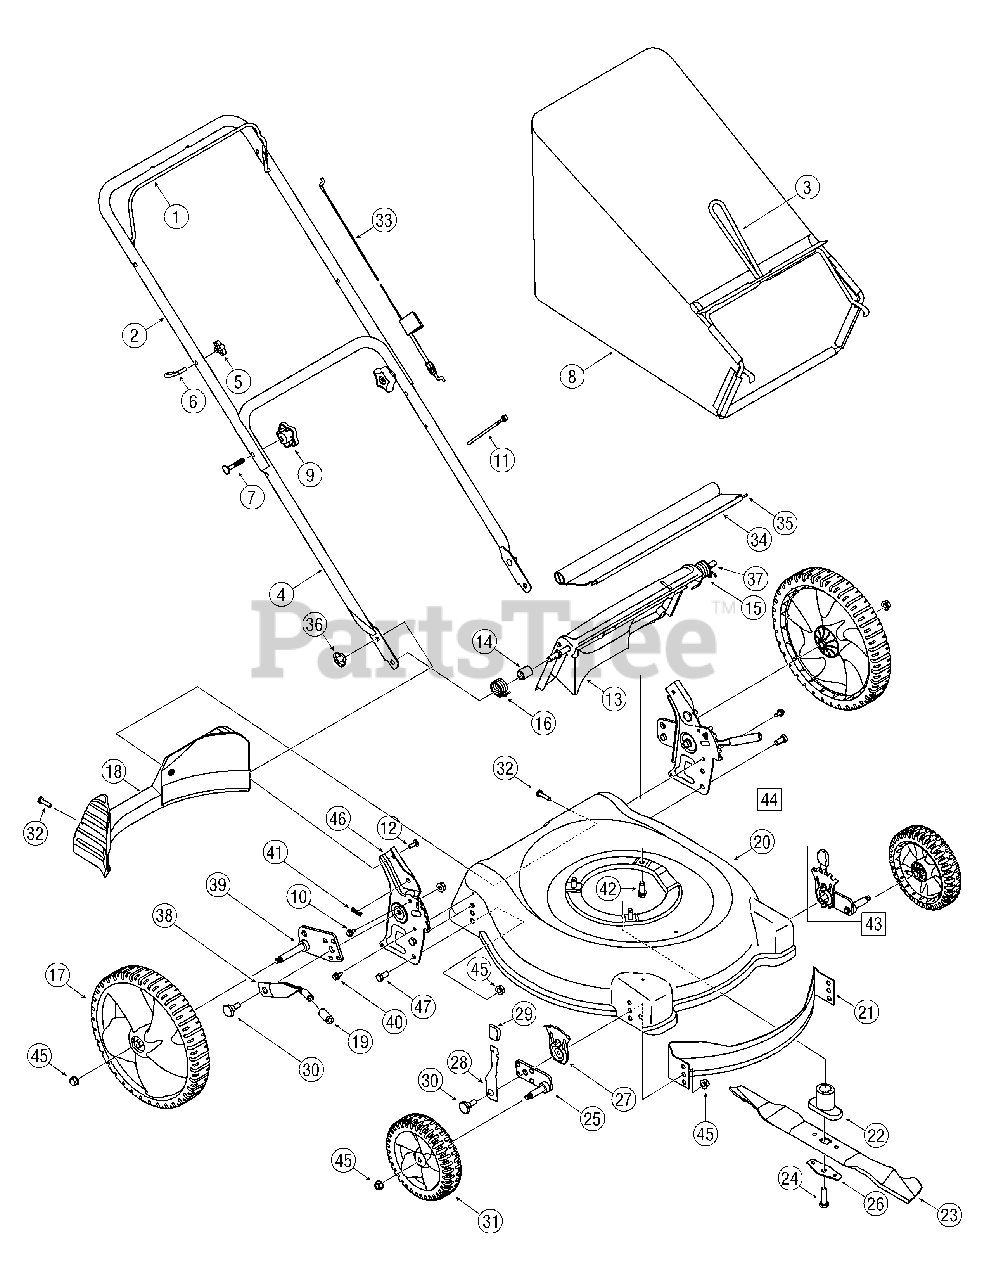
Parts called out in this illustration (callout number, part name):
5	Wing Nut
6	Rope Guide
7	Carriage Bolt, 5/16-18 x 2
8	Grass Bag Assembly
9	Star Knob
10	Screw, 1/4-20 x .500
11	Cable Tie
12	Carriage Bolt ,1/4-20
13	Rear Discharge Door
14	Spacer
15	Torsion Spring - LH
16	Torsion Spring - RH
17	Rear Wheel, 12" x 1.8"
18	Rear Baffle
19	Spring Lever Grip
21	Front Baffle
22	Blade Adapter
23	Mulching Blade
24	Hex Screw , 3/8-24 x 2.5
25	Pivot Arm Assembly - RH
25	Pivot Arm Assembly - LH
26	Blade Bell Support
27	Front Adjustment Plate
28	Adjustment Lever Knob
29	Spring Lever
30	Shoulder Screw
31	Front Wheel, 7" x 1.8"
32	Screw, 1/4-15 x 1.250
33	Control Cable - 40.5"
34	Trailshield
35	Trailshield Wire
36	Wing Nut, 1/4-20
37	Rear Door Pivot Rod
38	Spring Lever
39	Pivot Arm Assembly - RH
39	Pivot Arm Assembly - LH
40	AB Screw
41	Hairpin Clip
42	TT Sems Screw, 3/8-16 x 1.0
43	Ht. Adj. Assy. Front - LH
43	Ht. Adj. Assy. Front - RH
44	Rear Handle Bracket Assy. - LH
44	Rear Handle Bracket Assy. - RH
45	Flange Lock Nut, 3/8-16
46	Handle Bracket Assembly - RH
46	Handle Bracket Assembly - LH
47	Hex Screw, 3/8-16 x 0.75
